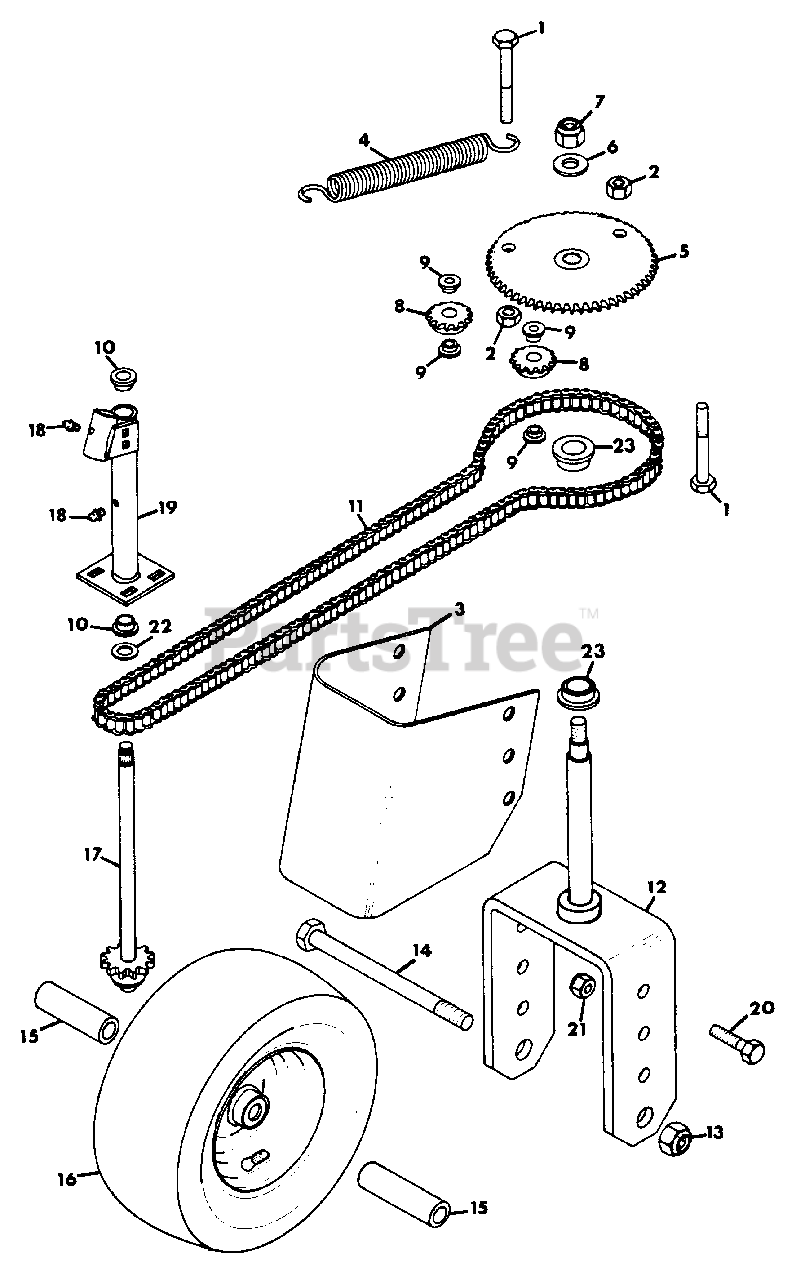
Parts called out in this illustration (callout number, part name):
1	BOLT, HEX 1/2-13X2.75
2	NUT, HEX 1/2-13
3	SHIELD, GRASS
4	SPRING
5	SPROCKET, 57-T #40
6	WASHER, FLAT .656X1.312X.095
7	NUT, LOCK 5/8-11
8	SPROCKET, DRIVE
9	BUSHING
10	BEARING, FLANGED
11	CHAIN, #40
12	FORK, WHEEL
13	NUT, LOCK 3/4
14	AXLE
15	SPACER, WHEEL
16	ASSEMBLY, WHEEL & TIRE 16X7.50-8
17	SHAFT, STEERING
18	FITTING, LUBE 1/2-28
19	TUBE, STEERING
20	BOLT, NEX 1/2-13X1.25
21	NUT, LOCK 1/2-13
22	BEARING, THRUST RACE
23	BEARING, FLANGED
